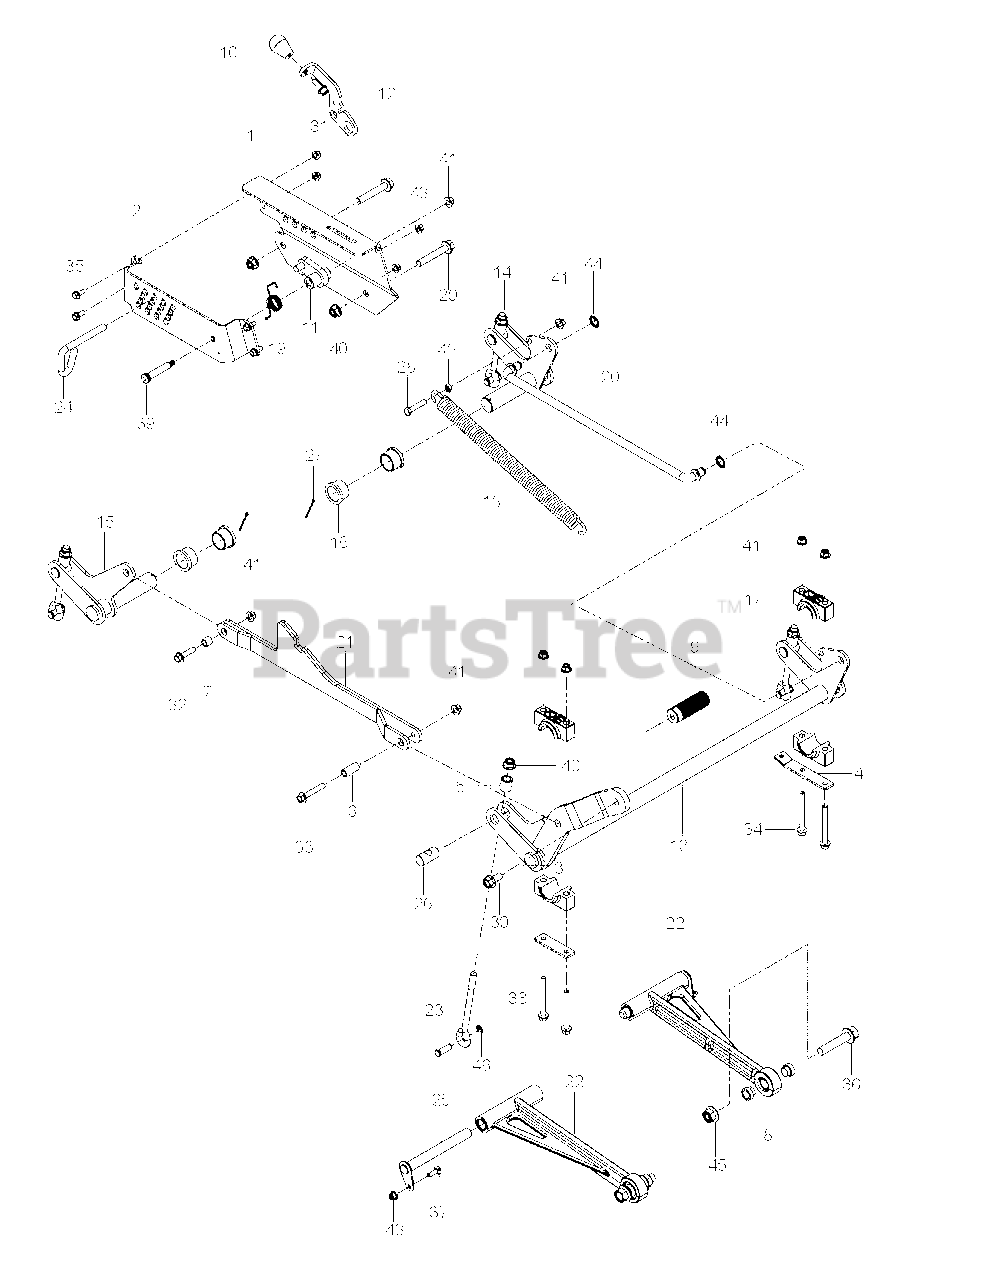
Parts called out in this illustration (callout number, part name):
1	PLATE, HEIGHT INNER ORG
2	PLATE, HEIGHT OUTER ORG
3	PLATE, PILLOW BLACK
4	PLATE, SPRING ANCHOR
5	SPACER, EYEBOLT
6	SPACER, FRONT LIFT STRAP
7	SPACER, REAR LIFT STRAP
8	SPACER, STRUT
9	PEDAL, DECK HEIGHT
10	KNOB - SHIFT
11	LATCH, TRANSPORT WLDMT
12	LEVER, TRANSPORT RELEASE
13	SHAFT DECK LIFT FT
14	SHAFT, LIFT LEFT REAR
15	SHAFT, LIFT RIGHT REAR
16	BUSHING, FLANGE 1.25 X 1.0
17	BLOCK, PILLOW
18	SPRING, EXTENSION
19	SPRING, TORSION
20	ROD, LIFT
21	WELDMT, DECK STRAP
22	ASSEMBLY, STRUT
23	PIN, 7/16 CLEVIS
24	PIN, HEIGHT
25	PIN, STRUT
26	PIN, TRUNION, EYEBOLT
27	COTTER PIN 1/8 X 2
28	HCS 3/8-16 X 1 3/4 GR5
29	HFFS 1/2-13 X 3 GD 5 ZD
30	HHFS 1/2-13 X 1 GR5 ZD
31	HHFS 3/8-16 X 1 GRD 5 ZD
32	HHFS 3/8-16 X 1.50 GR5 ZD
33	HHFS 3/8-16 X 2-1/4 GR 5 ZD
34	HHFS 3/8-16 X 3.5 GD 5 ZD
35	HHFS 5/16-18 X 3/4
36	HHFS 5/8-11 X 3.0 GD 8 ZD
37	RHSNB 5/16C X 1
38	EYEBOLT, DECK LIFT
39	BOLT, SHOULDER, 1/2 X 2.25
40	NUT, 1/2-13 HEX FLG NYLOC ZD
41	NUT 3/8-16 HEX FLG NYLOC ZD
42	NUT 3/8-16 HEX JAM
43	5/16-18 NYLOC FLANGE NUT
44	NUT 5/8 PUSH
45	NUT 5/8-11 FLG NYLOC ZD
46	RING, E, 7/16
